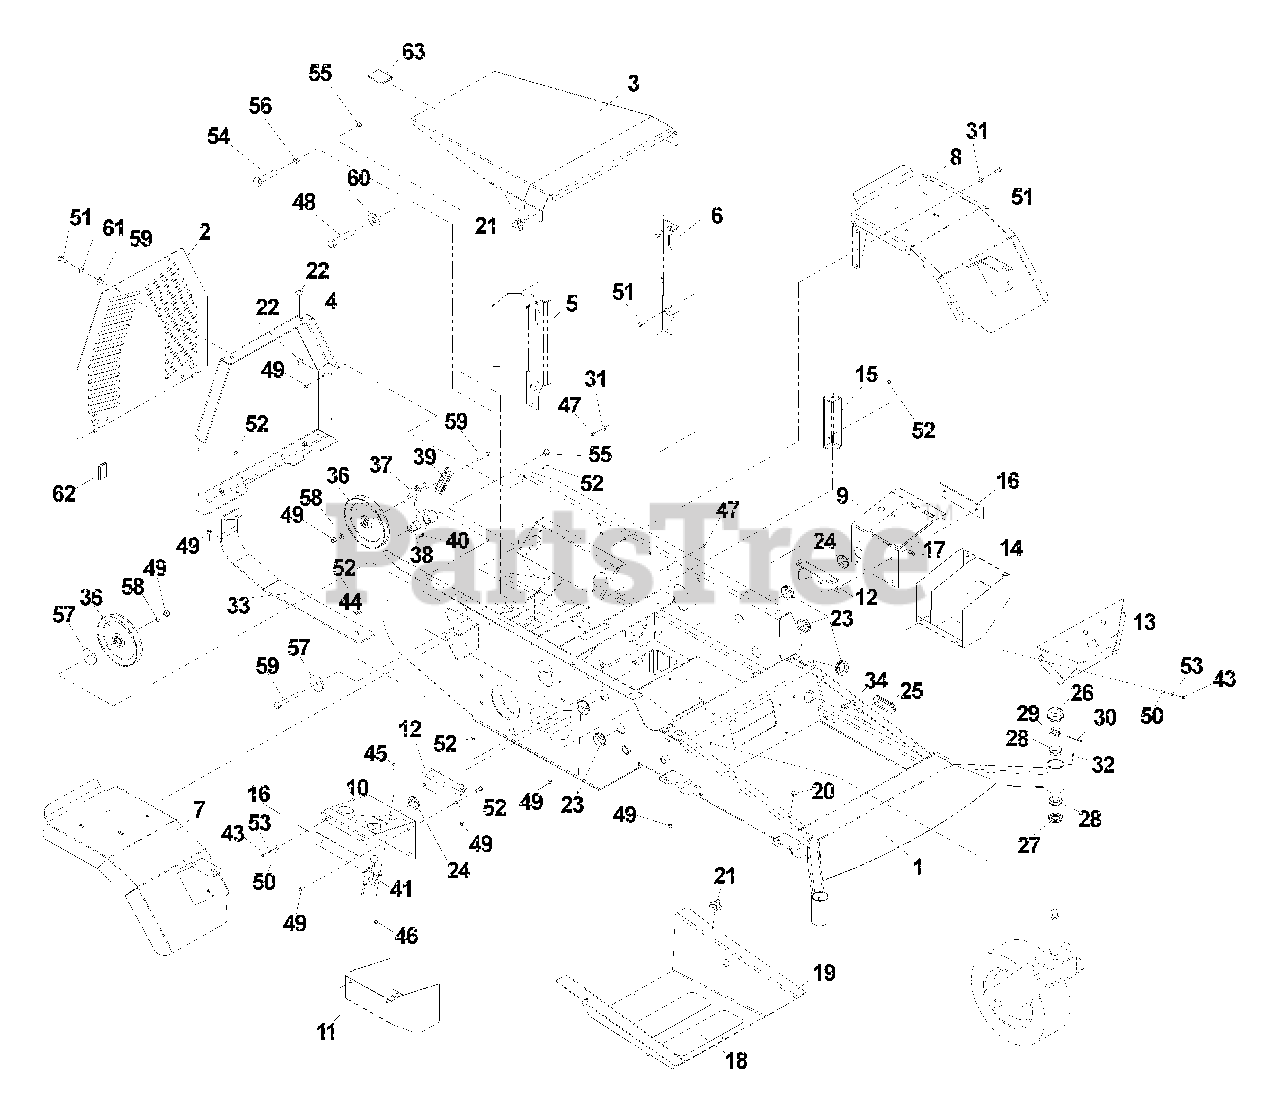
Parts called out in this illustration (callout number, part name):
1	Frame w/decals
2	Panel, back, w/decals
4	Frame, rear
5	Support, right
6	Support, left
7	Fender, right
8	Fender, left
9	Panel, top left
10	Console, top
11	Console, bottom
12	Bracket, angle
14	Console, bottom
17	Latch, magnetic
18	Pad, abrasive
19	Pan, floor
20	Stop, rubber
21	Knob w/stud
22	Grommet, bumper
26	Cap, grease
29	Nut, 1-14, slotted jam
30	Pin, cotter, 1/8 x 2
31	Washer, 5/16, SAE
33	Plate, skid
34	Retainer Nut, 5/16-18 U-Type
40	Zerk
41	Cable, throttle
43	Screw, 1/4-20 x 5/8, self-tapping
44	Washer, 3/8
45	Bolt, #10-24 x 1/2
46	Nut, #10-24, nyloc
47	Nut, 5/16-18, nyloc
48	Bolt, 1/2-13 x 2 3/4
49	Nut, 3/8-16, nyloc
50	Washer, 1/4
51	Bolt, 5/16-18 x 1
52	Bolt, 3/8-16 x 1
53	Lockwasher, 1/4
54	Bolt, 1/2-20 x 2, Gr.8,
55	Nut, 1/2-20, nyloc,
56	Nut, 1/2-20,
57	Washer, heavy
58	Washer, 3/8
59	Washer, 5/16
60	Washer, 1/2
61	Lockwasher, 5/16
